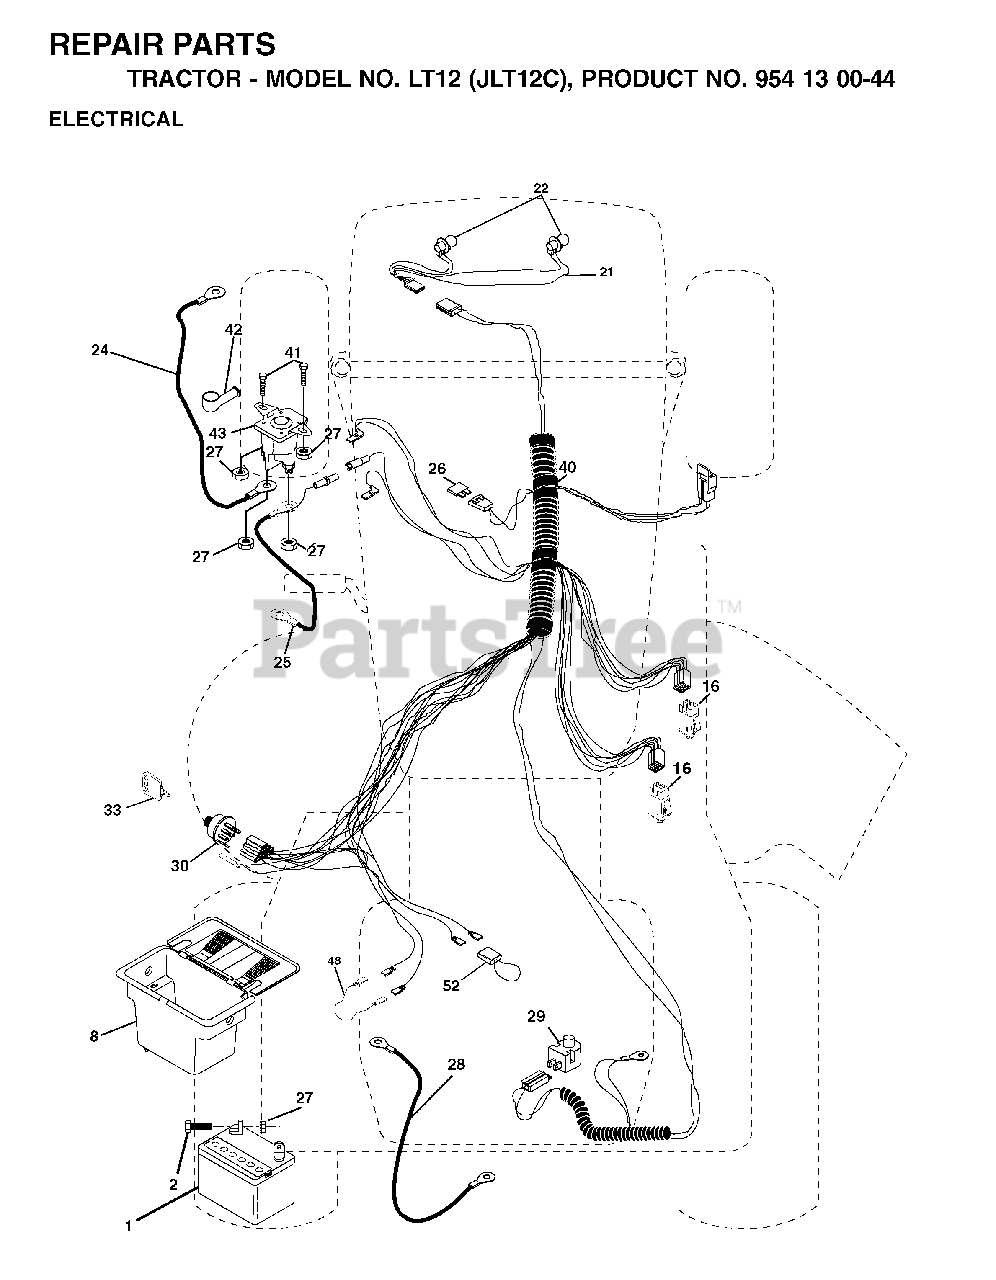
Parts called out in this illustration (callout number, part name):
1	BATTERY 12 VOLT 25 AMP
8	CASE BATTERY MECH HINGE
16	SWITCH INTERLOCK
21	HARNESS.W/LIGHT SOCKET
22	LIGHTBULB
24	BATTERY CABLE GT
25	CABLE BATTERY
26	FUSE 20AMP
27	NUT
28	CABLE T
29	SWITCH SEAT
30	IGNITION SWITCH
33	KEY MLD GEN DELTA
40	CABLE, IGN. HARNESS
42	TERMINAL COVER
43	SOLENOID
52	WIRE PROTECTION LOOP
